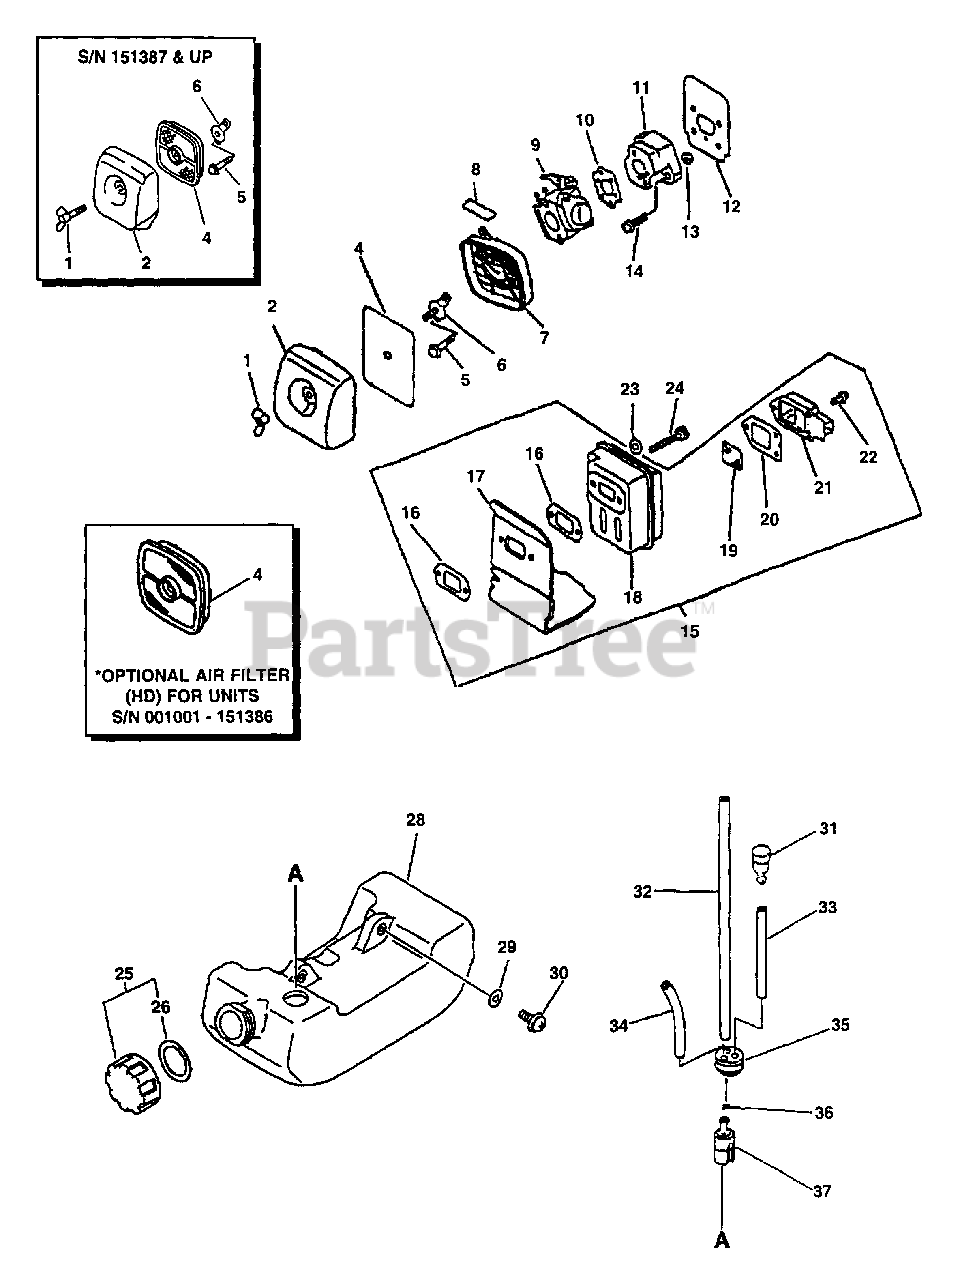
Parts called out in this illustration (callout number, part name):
1	WINGNUT - 6
1	THUMBSCREW
2	COVER, AIR FILTER
2	COVER, AIR FILTER - GRAY
4	FILTER, AIR
4	FILTER, AIR - SINGLE LAYER
5	SCREW - 5X65
6	PLATE, PREVENT
7	AIR FILTER CASE ASSY
8	LABEL - CHOKE
9	CARBURETOR C1U-K29
9	CARBURETOR C1U-K47
10	GASKET, INTAKE
11	INSULATOR, INTAKE
12	SHIELD, INTAKE
14	SCREW - 5X20
15	MUFFLER ASSY
16	GASKET, EXHAUST
17	COVER, EXHAUST
19	SCREEN, SPARK ARRESTOR
20	GASKET, EXHAUST
21	GUIDE, EXHAUST - OUTER
22	SCREW - 4X10
23	WASHER - 5
24	SCREW - 5X55
25	CAP ASSY
26	GASKET, CAP
28	TANK, FUEL
29	WASHER - 5
30	SCREW - 5X16
31	VENT, FUEL TANK
32	PIPE - 3X5X180 -- BLACK
33	PIPE - 3X5X70 -- BLACK
34	PIPE - 3X6X80 -- CLEAR
35	GROMMET
36	CLIP - 6
37	FILTER, FUEL
